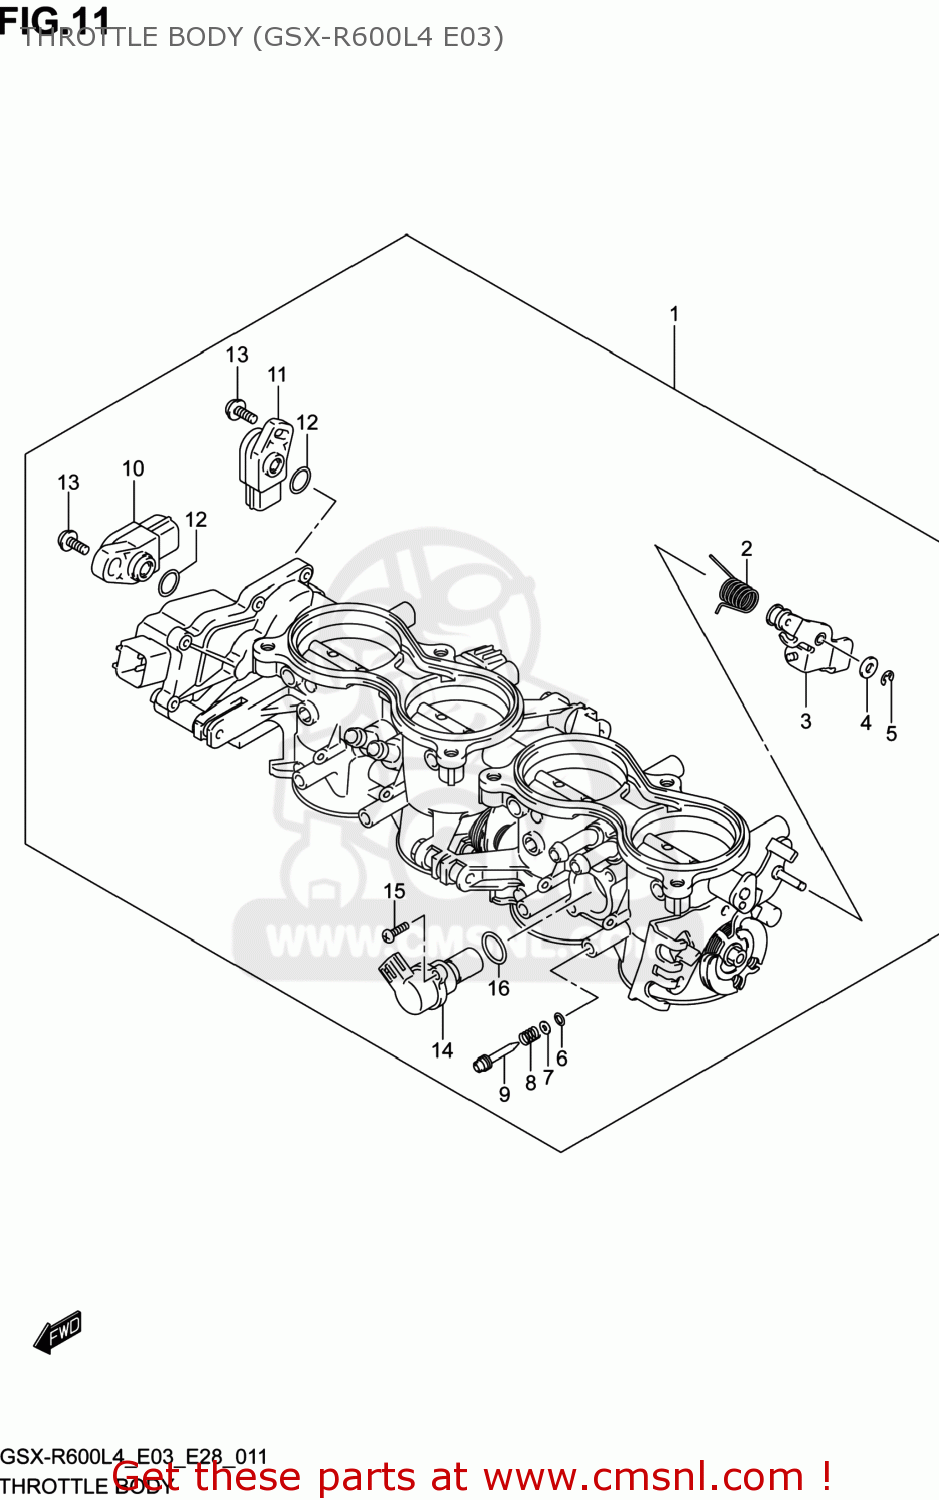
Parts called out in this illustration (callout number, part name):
1	BODY ASSY,THROTTLE
2	SPRING,TORSION
3	LEVER ASSY,LINK
4	PACKING (NAS)
5	E RING
6	O RING,PILOT AIR SCREW
7	WASHER
8	SPRING,THROTTLE SCREW
9	SCREW
10	SENSOR
11	SENSOR
12	O RING
13	SCREW
14	MOTOR ASSY
15	SCREW
16	O RING
